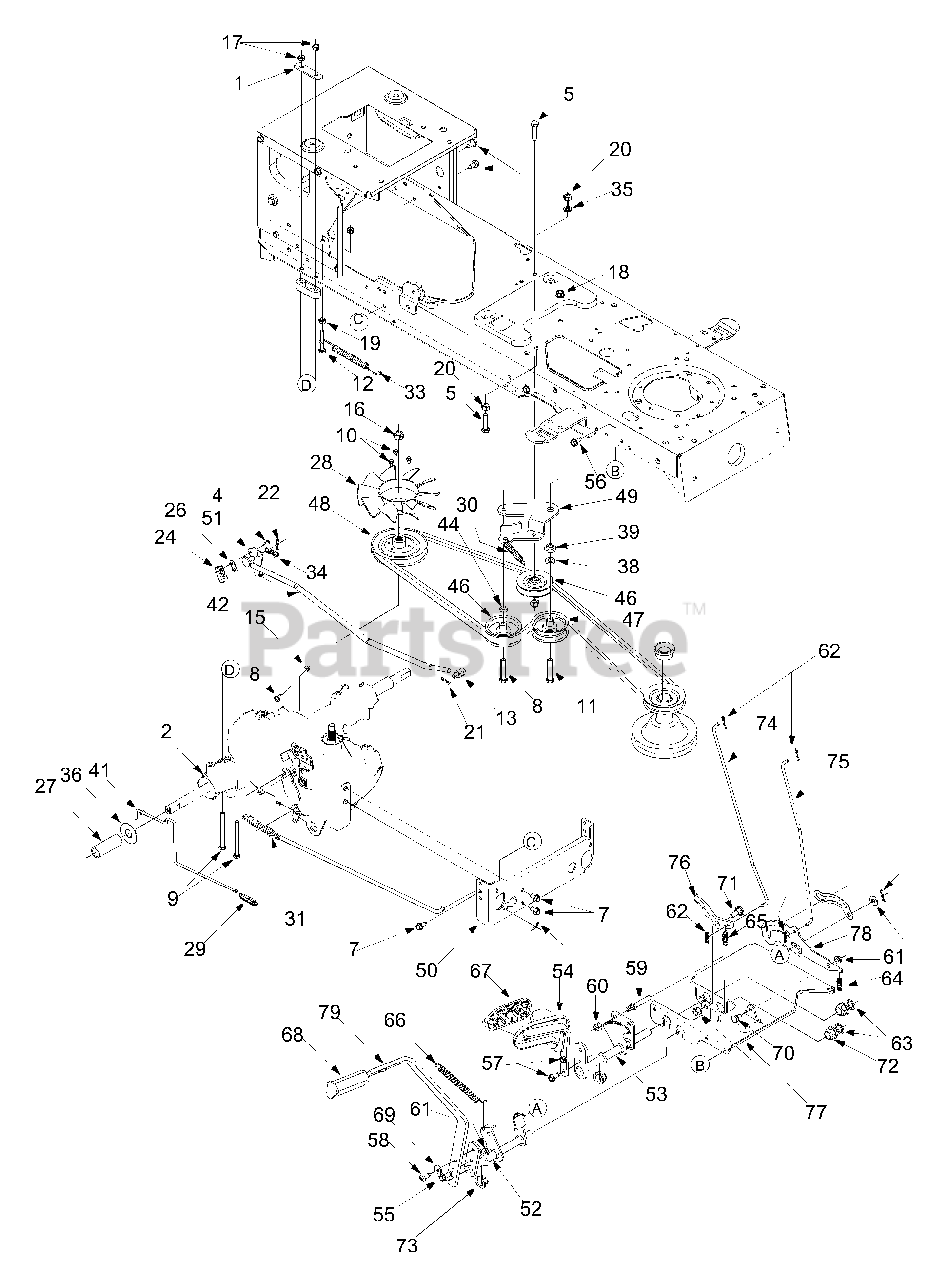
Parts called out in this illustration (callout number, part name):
2	Transmission: Hydrostatic
3	Harness Assembly
4	AB Screw #8-18 x 0.5
5	Hex Bolt 3/8-16 x 1.5
6	TT Screw 1/4-20 x 0.5
7	AB Screw 5/16-12 x 0.75
8	TT Sems Screw 3/8-16 x 1.5
9	Hex Bolt 5/16-18 x 3.5
10	Carriage Screw
11	Hex Bolt 3/8-16 x 2.25
12	Hex Bolt 5/16-18 x 2.0
13	Ferrule
14	Hex Lock Nut 3/8-16
15	Hex Lock Nut 1/4-20
16	Hex Nut 1/2-20
17	Hex Lock Nut 5/16-18
18	Flanged Lock Nut 3/8-16
19	Hex Nut 5/16-18
20	Hex Nut 3/8-16
26	Plate: Insulator Nut
27	Sleve: 0.758 x 0.821 x 1.5
28	Fan: Blade
29	Extension Spring
30	Extension Spring
31	Extension Spring
33	Extension Spring
34	Extension Spring
39	Shoulder Spacer
43	Spacer: Transaxle
44	Spacer
45	V Belt
46	Idler Pulley
47	Flat Idler Pulley
48	Input Pulley
52	Control Assembly: Brake
55	TT Screw 5/16-18 x 0.875
56	AB Screw 5/16-12 x 0.75
57	LD Screw 5/16-18 x 0.75
58	TT Screw 5/16-18 x 0.75
59	Pin
60	Hex Lock Nut
61	Flange Lock Nut 5/16-18
63	Push Nut
64	Compression Spring
65	Extension Spring
66	Extension Spring
67	Control Pedal
68	Brake Control Pedal
69	Flat Washer
70	Shoulder Screw
71	Shoulder Screw
72	Hex Flange Bearing
73	Hex Flange Bearing
74	Control Rod: Brake Lock
75	Cruise Control Rod
76	Cruise Latch
78	Lockout Bracket
